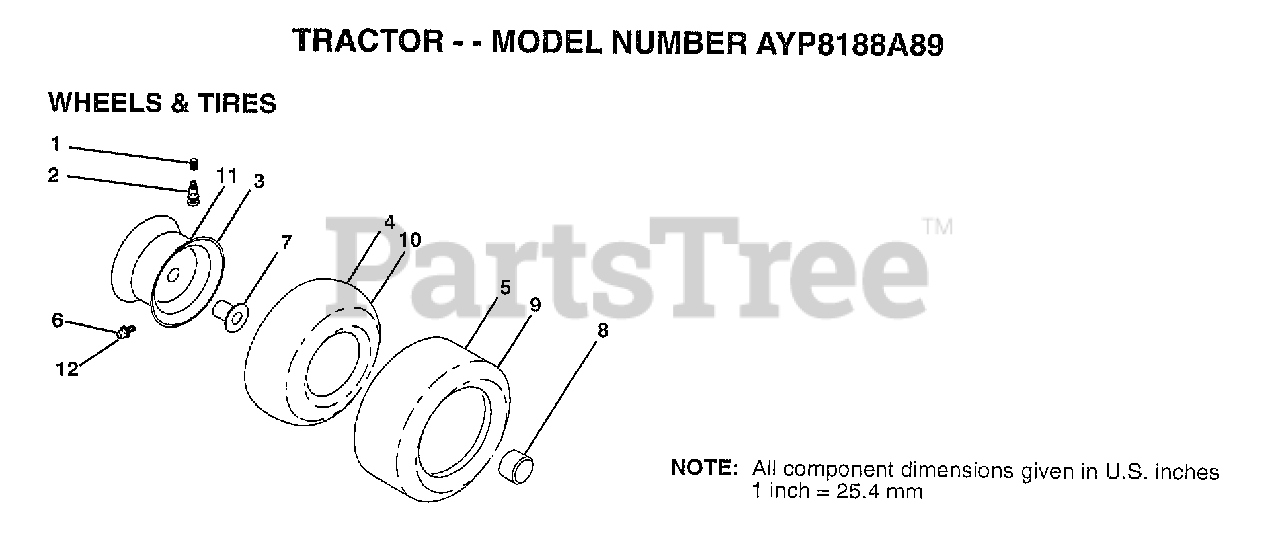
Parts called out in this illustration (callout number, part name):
1	VALVE CAP
2	VALVE STEM LT
3	"RIM ASM 8"" FRT"
4	TUBE.16X6.5/7.5-8
6	FITTING LT
7	"FLANGE, BEARING"
8	HUB CAP
10	TUBE.23X8/10-12
11	"RIM ASM 12"" REAR"
12	ZERK FITTING M
